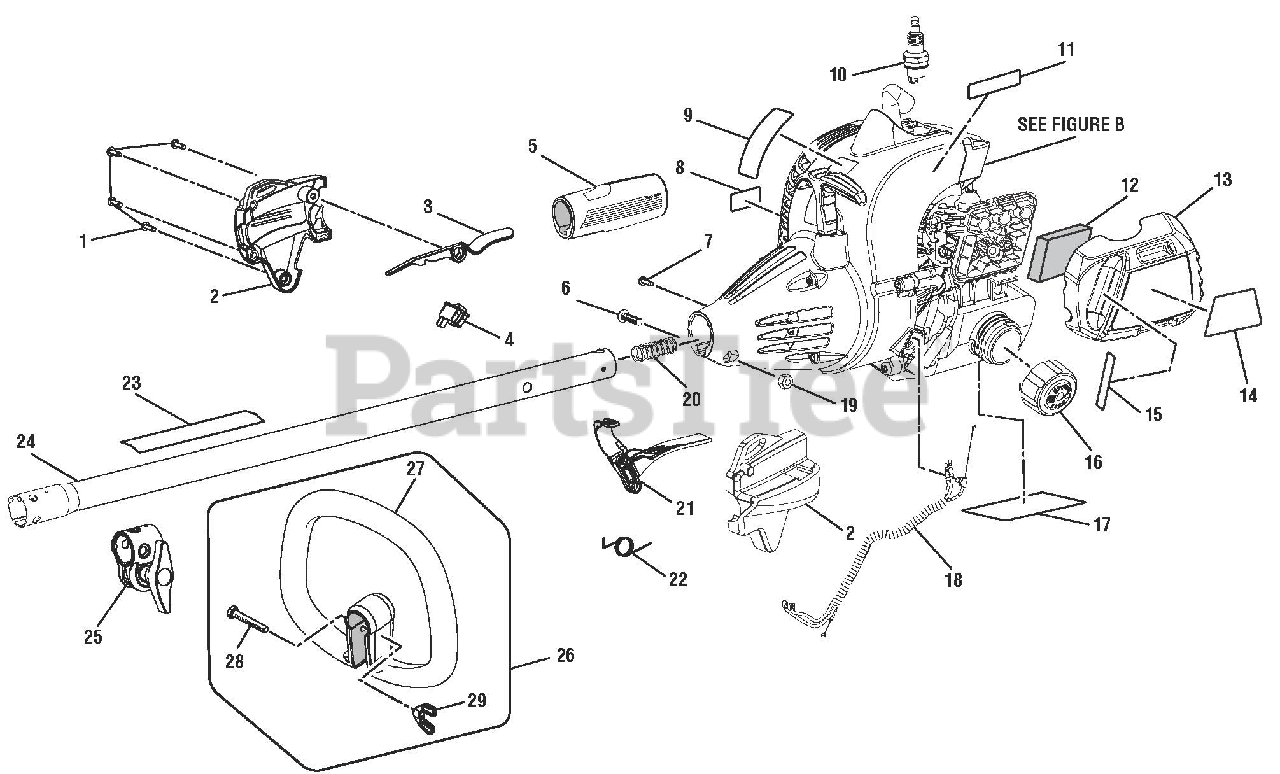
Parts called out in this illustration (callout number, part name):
1	Screw (M4 x 20 mm)
2	Control Handle Assembly
3	Trigger Lock
4	Switch (Momentary Contact)
5	Rear Handle Grip
6	Bolt (M6 x 20 mm)
7	Screw (M4 x 8 mm, T20 Torx Hd.)
8	Combustion Warning Label
9	Logo Label
10	Spark Plug (Champion RCJ6Y)
11	Primer Label
12	Air Filter
13	Air Box Cover
14	Starting Instructions Label
15	Run Start Label
16	Fuel Cap Assembly (1.5 in. Diameter)
17	Fuel Tank Warning Label
18	Throttle and Lead Assembly
19	Hex Nut (M6)
20	Compression Spring
21	Throttle Trigger
22	Throttle Spring
23	Warning Decal
24	Upper Boom Assembly
25	Boom Clamp Assembly
26	Front Handle Assembly
27	Front Handle
28	Bolt (1/4-20 x 40 mm)
29	Wing Nut (1/4-20)
